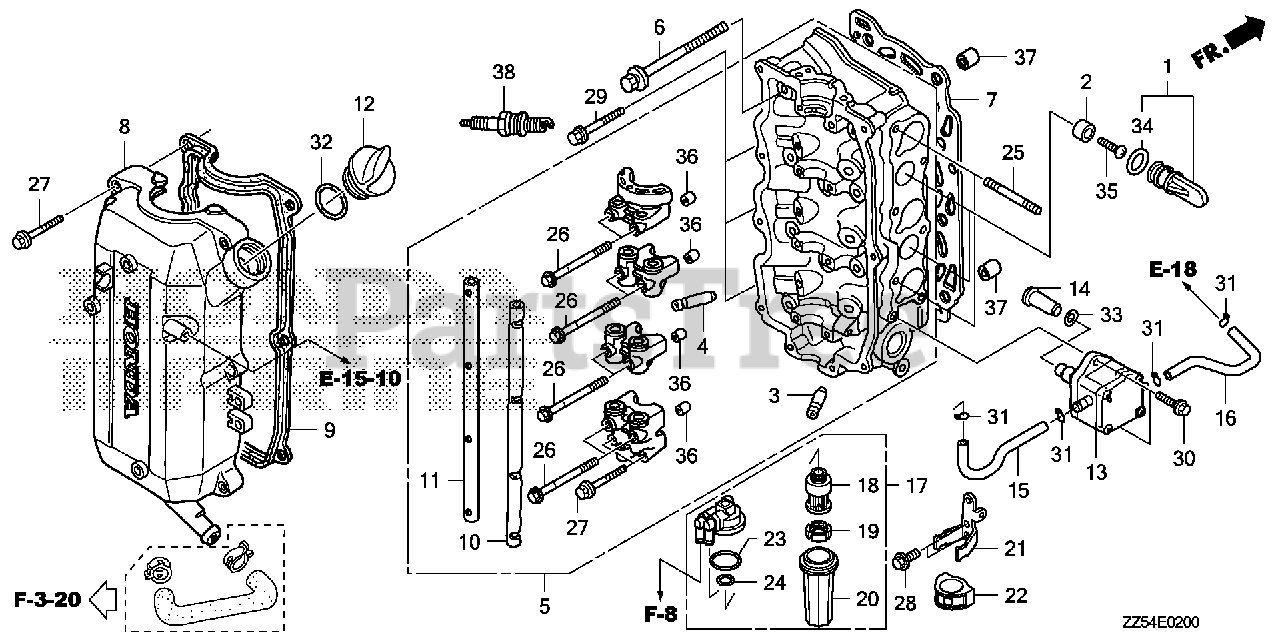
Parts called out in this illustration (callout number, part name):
1	CAP ASSY., ANODE METAL
2	METAL KIT, ANODE
2	METAL, ANODE
3	GUIDE, VALVE (OVER SIZE)
4	GUIDE, VALVE (OVER SIZE) (EXHAUST SIDE)
5	CYLINDER HEAD ASSY. *NH8* (DARK GRAY)
6	BOLT-WASHER (10X85)
7	GASKET, CYLINDER HEAD
8	COVER, CYLINDER HEAD
9	GASKET, HEAD COVER
10	SHAFT, IN. ROCKER ARM
11	SHAFT, EX. ROCKER ARM
12	CAP, OIL
13	PUMP ASSY., FUEL (MSDS)
14	LIFTER, FUEL PUMP
15	TUBE B, FUEL (FKM)
15	TUBE B, FUEL
16	TUBE C, FUEL (FKM)
16	TUBE C, FUEL
17	FILTER ASSY., FUEL
21	STAY, FUEL STRAINER
22	SUSPENSION, STRAINER
25	BOLT, STUD (6X28)
26	BOLT, FLANGE (6X70)
27	BOLT, FLANGE (6X35)
28	BOLT, FLANGE (6X14)
29	BOLT, FLANGE (8X40)
30	BOLT, FLANGE (6X20) (SH)
31	CLIP, TUBE (B12)
32	O-RING (26X2.7)
33	O-RING (20.8X2.4)
34	O-RING (19.8X2.4)
35	SCREW, PAN (5X20)
36	PIN A, DOWEL (8X14)
37	PIN A, DOWEL (12X16)
38	SPARK PLUG (X22ESR-UB)
38	SPARK PLUG (DR7EB)
